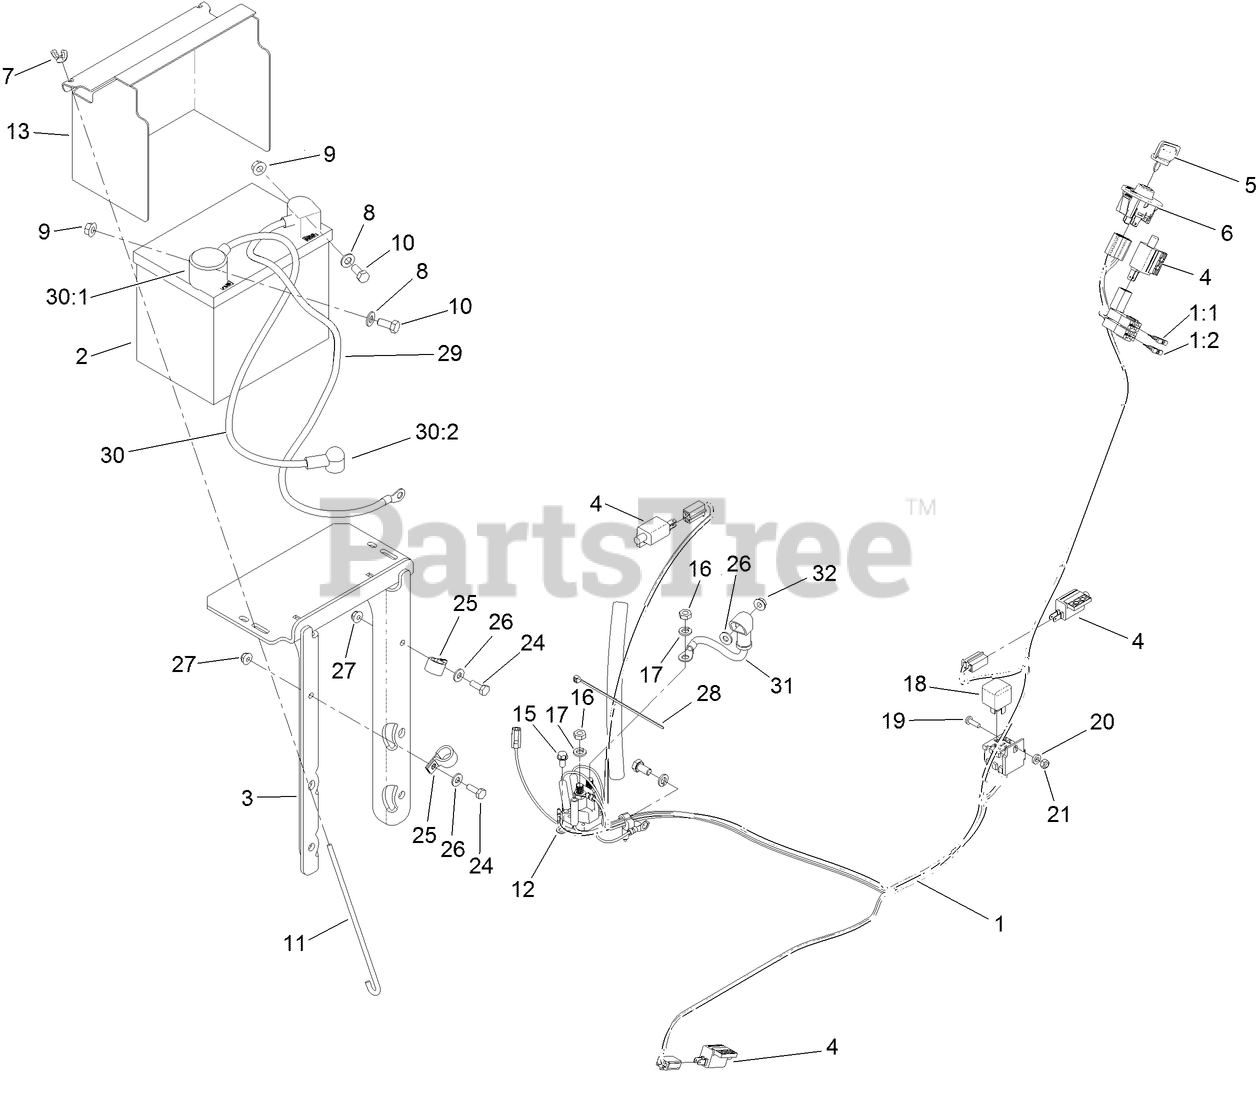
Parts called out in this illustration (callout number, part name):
1	HARNESS-WIRE
1:1	FUSE-BLADE, 30 AMP
1:2	FUSE-BLADE, 25 AMP
2	BATTERY-DRY
3	TRAY-BATTERY
4	SWITCH-OPEN, NORMALLY
5	KEY-IGNITION
6	SWITCH-IGNITION
7	WINGNUT
8	WASHER-PLAIN
9	NUT-HHF, SMOOTH
10	SCREW-HH
11	BOLT-HOLDDOWN
12	SOLENOID
13	COVER-BATTERY
15	SCREW-HWH
16	NUT-JAM
17	WASHER-LOCK
18	RELAY
19	SCREW-PPH
20	WASHER
21	NUT-LOCK, NI
24	SCREW-HH
25	CLAMP-CABLE
26	WASHER-FLAT
27	NUT-HF
28	TIE-CABLE
29	CABLE-BATTERY, BLACK
30	POSITIVE BATTERY CABLE ASM
30:1	INSULATOR-BATTERY
30:2	INSULATOR-SOLENOID
31	CABLE-BATTERY, RED
32	NUT-HF
